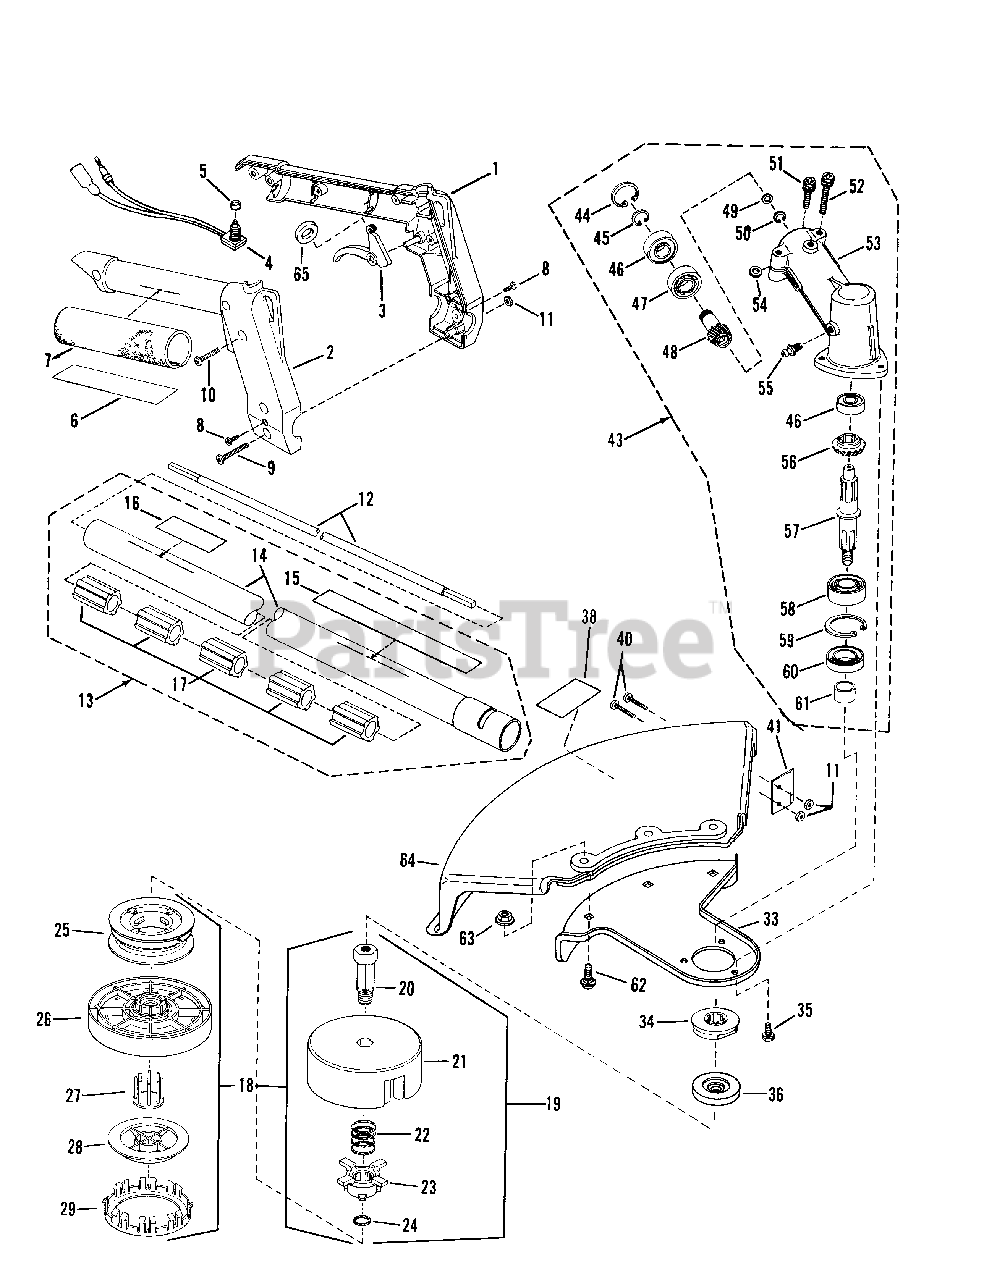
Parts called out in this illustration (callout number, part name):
1	HANDLE, Left Half
2	HANDLE, Right Half
3	TRIGGER
4	SWITCH
5	CAP, Switch
6	STRIP, Adhesive
7	GRIP, Handle
8	SCREW, TORX, #6 x 5/16"
9	SCREW, #10-32 x 7/8"
10	SCREW, #10-16 x 3/4"
11	LOCKNUT, #10-32
12	SHAFT, Main (55.12"x.25", .2" square ends x 1")
13	ASSEMBLY, Tubing 8 Bushing
14	TUBE
15	DECAL - SNAPPER
16	DECAL - WARNING (Eye Protection)
17	ISO BUSHING
18	ASSM'Y.,Tap Head, Left Hand
19	ASSM'Y, Housing
21	HOUSING
23	INDEXER
24	RETAINER, Wire
25	SPOOL W/LINE
27	ACTUATOR
29	RETAINER, Knob
33	SHIELD, Steel
34	HOLDER "A"
35	BOLT, M5 x 10mm
36	HOLDER "B"
37	SHIELD
38	DECAL, Replacement Part
40	SCREW, #10-32 x 3/8
41	CUTTER, Line
43	GEAR HEAD ASSM'Y.,
44	SNAP-RING, 26mm
45	SNAP-RING, 10mm
46	BEARING
47	BEARING
48	BEVEL PINION
49	WASHER, Flat
50	SNAP-RING, 10mm
51	BOLT, M5 x 12mm Hex Hd.
52	BOLT, M5 x 25mm H.H.
53	GEAR CASE
55	FITTING, Lube
56	BEVEL GEAR
57	SPLINE SHAFT
58	BEARING
59	SNAP-RING, 35mm
60	SEAL, Oil
61	SPLINE SLEEVE
62	CARRIAGE BOLT, 1/4-20 x 5/8
63	NUT, 1/4-20 Hex Lock
64	EXTENTION, Plastic Shield
65	"O" RING
